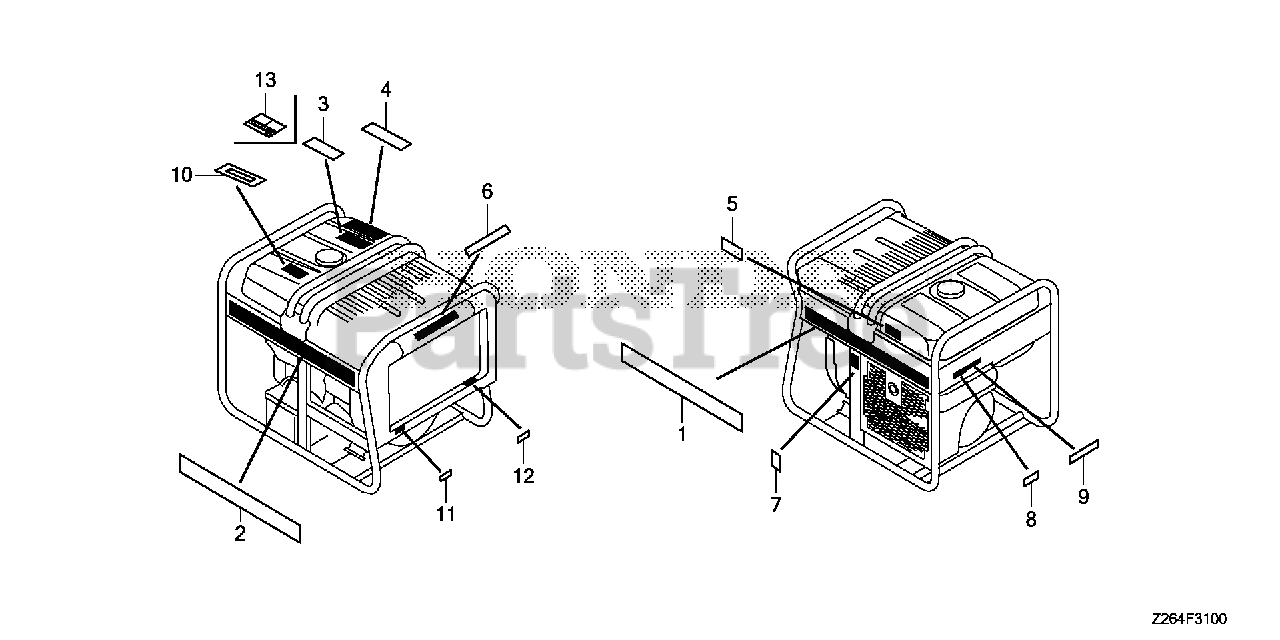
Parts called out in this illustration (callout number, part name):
1	MARK, R. EMBLEM (EB10000)
2	MARK, L. EMBLEM (EB10000)
4	MARK, CAUTION (A)
5	MARK, SPECIFICATION (A)
6	MARK, HONDA
7	MARK, EX. CAUTION (A)
8	MARK, EX. CAUTION
10	PLATE, FUEL INDICATION
11	MARK, FUEL PETCOCK
13	MARK, CPSC (CO CAUTION)
